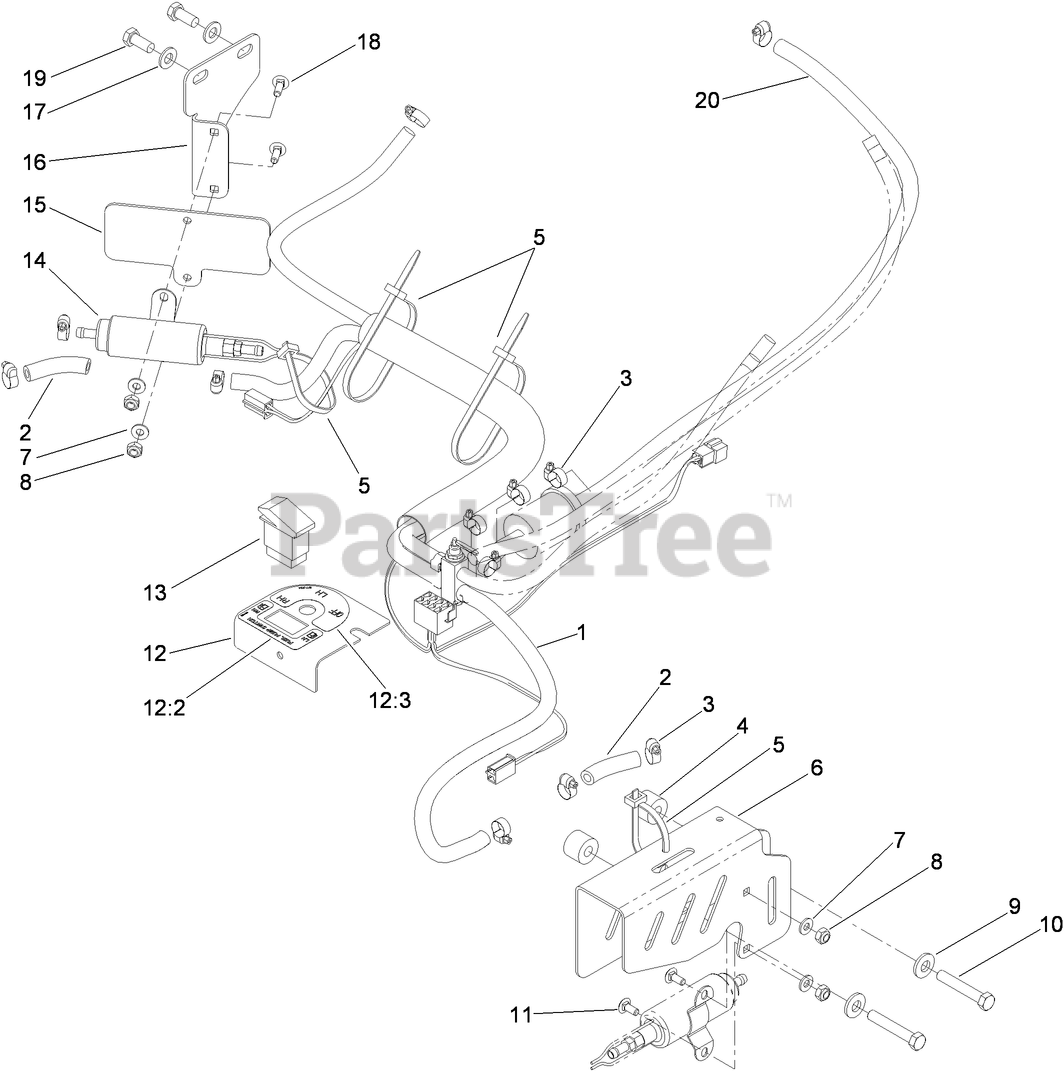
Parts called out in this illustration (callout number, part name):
1	FUEL VALVE AND HOSE ASM
2	HOSE-FUEL
3	CLAMP-WORM
4	SPACER
5	TIE-PLASTIC
6	BRACKET-FUEL PUMP, LH
7	WASHER-FLAT
8	NUT-LOCK, NI
9	WASHER-BELLEVILLE
10	SCREW-HH
11	SCREW-CARR
12	FUEL VALVE BRACKET ASM
12:2	DECAL-SWITCH, FUEL
12:3	DECAL-VALVE, FUEL
13	SWITCH
14	PUMP-FUEL
15	PLATE-COVER, FUEL PUMP
16	BRACKET-FUEL PUMP, RH
17	WASHER-FLAT
18	BOLT-CARR
19	SCREW-HH
20	HOSE-FUEL
